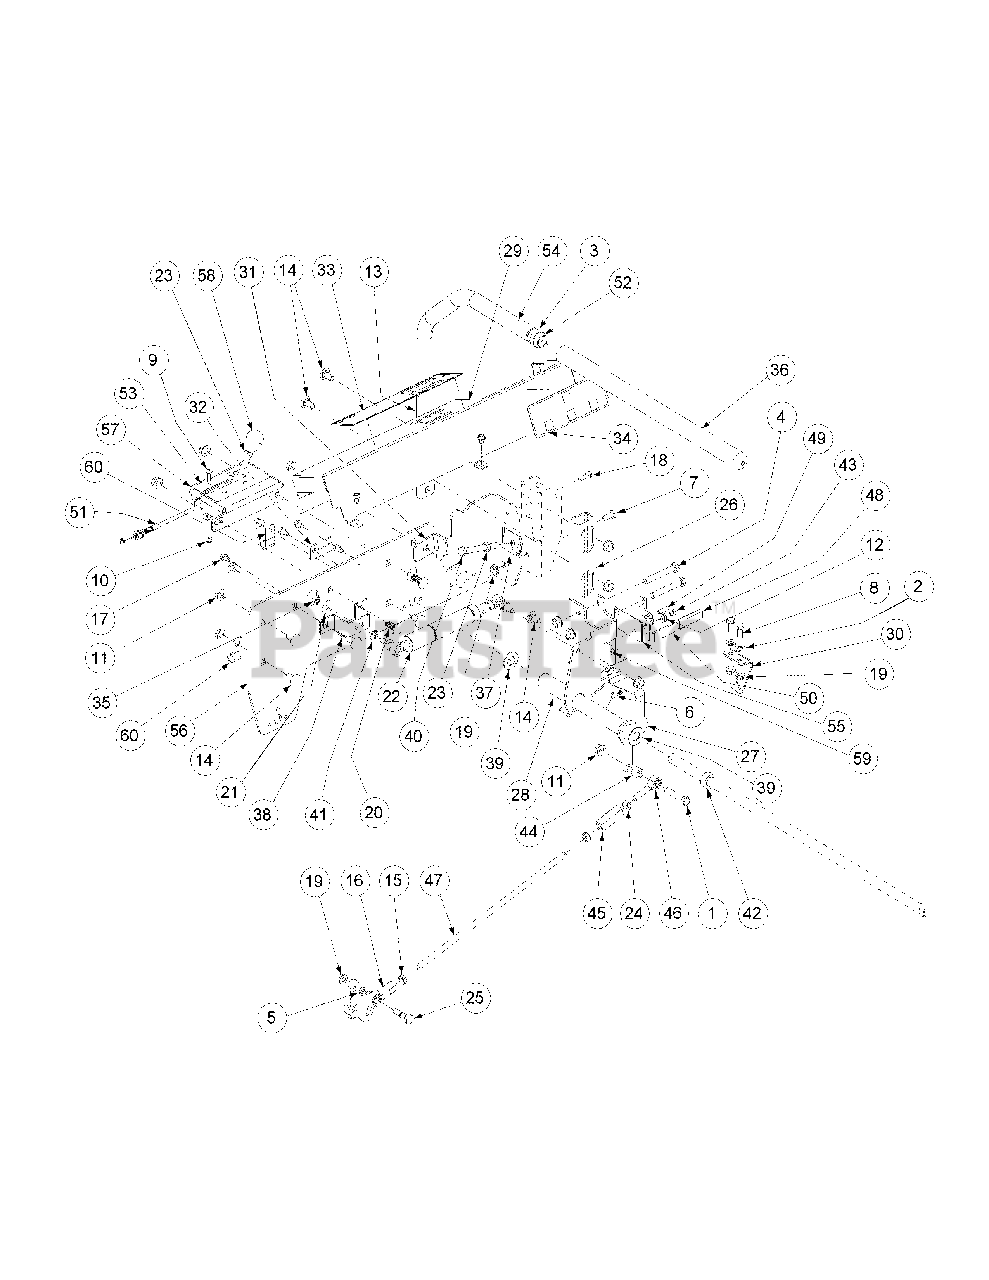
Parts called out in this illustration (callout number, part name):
1	Capscrew, 3/8-16 x 1-3/4
2	Flat Washer, 5/16
3	Lock Washer, Ignition Switch
4	HHCS, 3/8-16, 2.5
5	5/16, Lock Washer
6	Grease Fitting, 90°, 1/4-28
7	HHCS, 5/16-18 x 1.0
8	Hex, Cap Screw, 5/16-18 x 3/4
9	Screw, Machine, 10-32 x 3/4
10	Nut, Lock, Nylon Insert, #10-32
11	Nut, Hex, Flange Lock, 3/8-16
12	Flat Washer, 1/4"
13	Split Conduit, 1/4" Poly
14	Carriage Bolt, 3/8-16 x .75 LG.
15	Hex Jam Nut, 3/8-24
16	B/Joint, 3/8-24, Right Hand Female
17	Screw, TT, 1/4-20, 0.5, Hex Index Washer
18	Screw, TT, 1/4-20, 0.75, Hex Index Washer
19	Nut, Lock, HexFlange, 5/16-18
20	Carriage Bolt, 3/8-16 x 1
21	Belle Washer, .325 x .930 x .045
22	Cylinder Return to Neutral Kit
23	Nut, 3/8-16, Jam
24	Nut, 3/8-24, Jam, LH Thrd
25	Screw, Shoulder Control Rod
26	Mounting Handle
27	Lever, Safety Switch
28	Hub Assy, Control LH Bearing
29	Control Panel, LH
30	Switch Mounting Bracket, Lapbar
32	Holder Shaft, Park Brake
33	Decal, Warning & Throttle
34	Decal, Left Hand Control
35	Nut, Hex, Center Lock, M8
36	Grip, 1.0
37	U-Nut, 3/8-16, .75
38	Bracket Assembly, Mount Dampener
39	Flat Washer, 5/8 Nylon
40	HHCS, 3/8-16, 3.00
41	External Tooth Washer, 3/8
42	Shaft Collar
43	Shoulder Bolt, 1/4x1/4
44	Spacer, .385ID x .625 OD x 50 Lg
45	Turnbuckle
46	B/Joint, 3/8-24, LH Male
47	Rod Connector 3/8 OD x 14.125
48	Grip, Speed Lever
49	Plunger, 1/4-20 x 3/4
50	Speed Control Adjuster Assembly, LH
51	Remote Deflector Cable
52	Lapbar Switch, On/Off
53	Decal, Side Deflector, On.Off
54	Lapbar Switch Handle Assembly, LH
55	Speed Control Detent Plate
56	Control Panel Mount, LH
57	Deflector Control Mounting Plate
58	Transmission Lever Knob
59	Nut, 10-24, w/Star Washer
60	Heat Shield Clip
